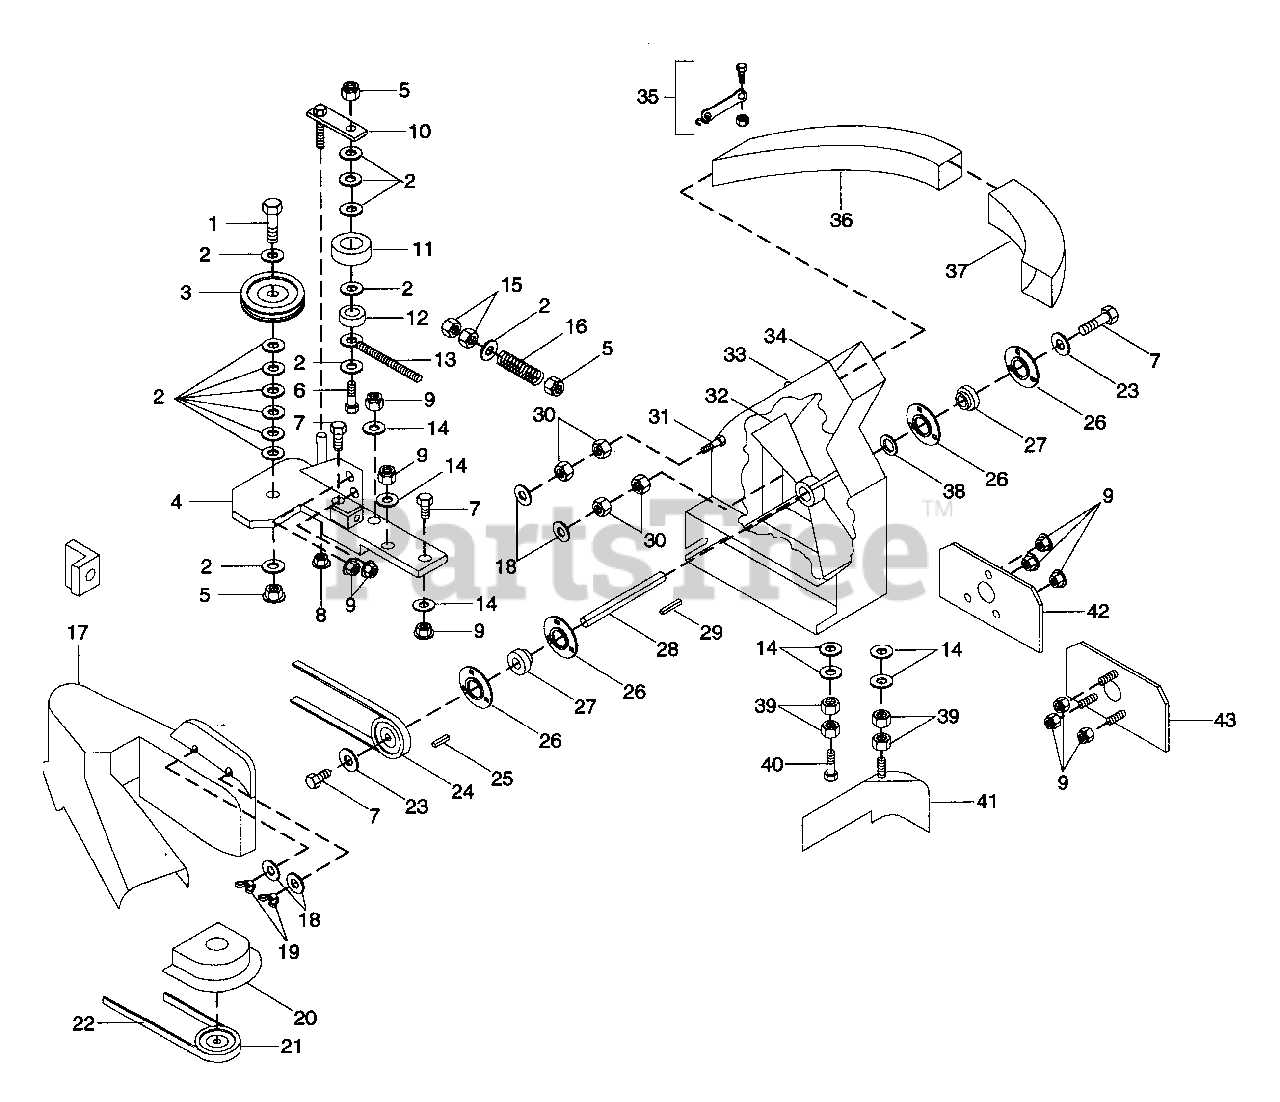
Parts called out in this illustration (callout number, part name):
1	BLT-HEX .38-16X1.75 PL GR5
2	WSHR-FL-STL .382X.812X.062
3	FLAT IDLER 6 1/4
4	BLOWER MOUNT PLATE
5	NUT-LK-NYL .375-16 PL
6	BLT-HEX .38-16X2.00 PL GR5
7	BLT-HEX .31-18X.75 PL GR5
8	NUT-LK-NYL .50-13 GR 5 PL
9	NUT-LK-NYL.312-18 PL
10	IDLER ARM
11	V-IDLER 5"
12	SPACER 3/8 ID
13	SPRING ROD
14	WSHR-FL-STL .344X1.375X.075 PL
15	NUT-HEX .375-16
17	BELT GUARD
18	WSHR-FL-STL .260X.500X.060 PL
19	NUT-WING .250-20 YWZC
20	BELT COVER - SMALL
21	DRIVE PULLEY
22	BELT,4L RAW COGGED
23	WSHR-FL-STL .328X1.0X.094 PL
24	DRIVEN PULLEY 3"
25	KEY-SQ .188X.50X.188
26	FLANGETTE
27	BEARING
29	KEY-SQ .188X2.0X.188 SAE 8630
30	NUT-HEX .250-20 PL
31	BLT-HEX .25-20X1.00 PL GR5
32	IMPELLER
33	ROPE TIE
34	BLOWER HOUSING
35	BUNGIE W/HOOK 6"
36	LONG CHUTE
37	SHORT CURVED CHUTE
38	NARROW MACHINE BUSHING 10-3/4
39	NUT-HEX .312-18
40	BLT-HEX .31-18X1.75 GR5
41	BAFFLE WELD'T 42"
42	WALL PLATE OUTER
43	WALL PLATE - INNER
